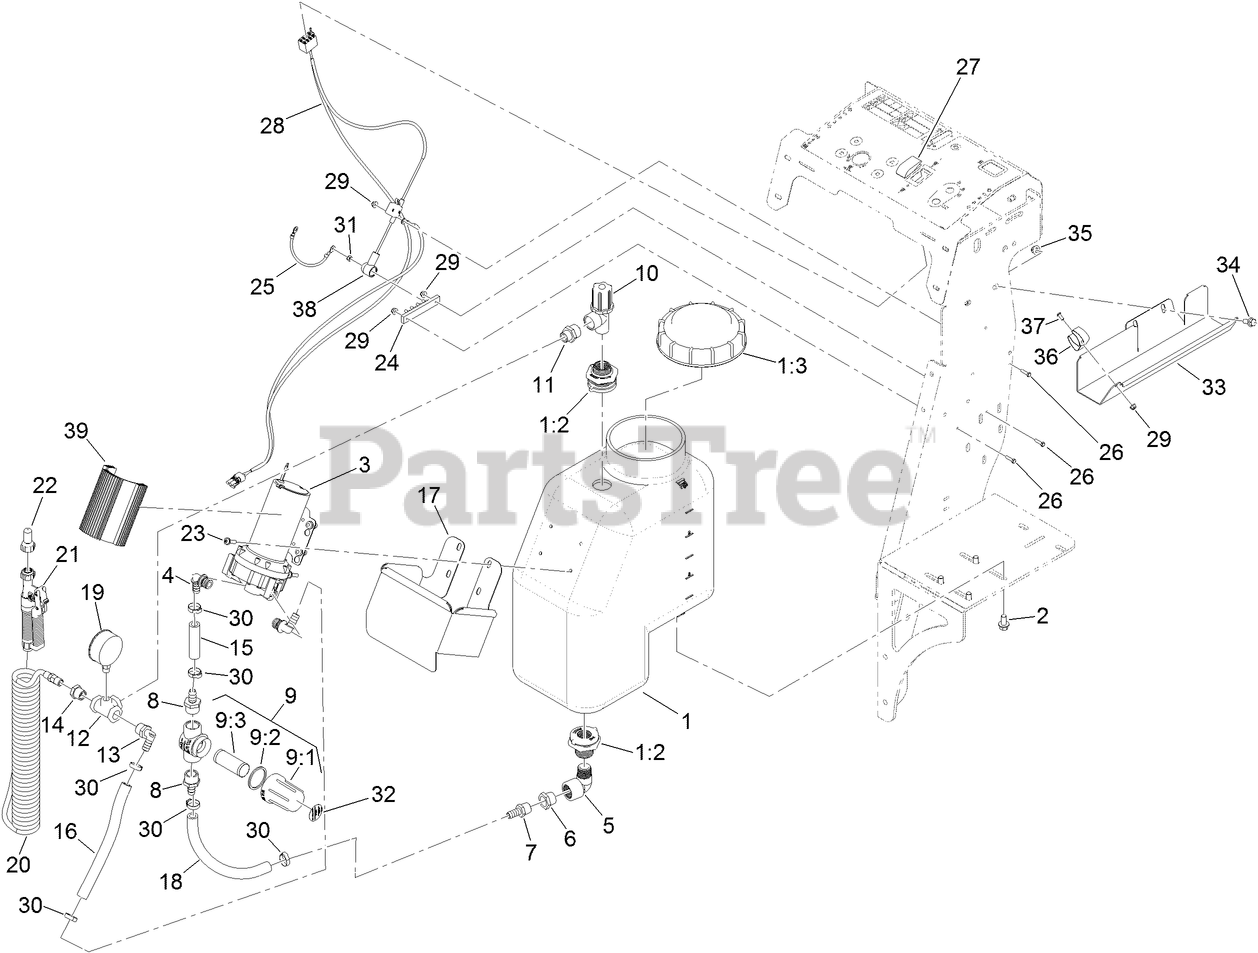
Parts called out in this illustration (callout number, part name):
1	ASM-TANK, ISO, 7GAL
1:2	FITTING-BULKHEAD
1:3	CAP-TANK, SPRAY
2	SCREW-HHF
3	PUMP-5.3 GPM
4	FITTING-ELBOW, BARBED
5	ELBOW-90 DEG
6	REDUCER-BUSHING, PLASTIC
7	FITTING-HOSEBARB
8	FITTING-STRAIGHT
9	STRAINER-INLINE
9:1	BOWL-STRAINER
9:2	GASKET-HEAD, LINE STRAINER
9:3	SCREEN-STRAINER, 50 MESH
10	VALVE-THROTTLE
11	FITTING-NIPPLE
12	FITTING-CROSS
13	FITTING-ELBOW, HOSEBARB
14	FITTING-REDUCER
15	HOSE-SPRAY
16	HOSE-SPRAY
17	GUARD-PUMP, ISO
18	HOSE-SPRAY
19	GAUGE-PLAIN
20	HOSE-COILED, 15 FT
21	GUN-SPRAY, SPOT
22	TIP-SPRAY, #12 SPOT
23	SCREW-HSBHF
24	BLOCK-TERMINAL
25	HARNESS-WIRE, JUMPER
26	SCREW-HH
27	SWITCH-ROCKER
28	HARNESS-ACCESSORY
29	NUT-HEX FLANGE
30	CLAMP-OETIKER, 167
31	NUT-HEX
32	DECAL-CAP, STRAINER
33	TRAY-GUN, 7GAL RT
34	SCREW-HHF
35	NUT-HEX FLANGE
36	HOLDER-TOOL, CLIP
37	SCREW-HSBH
38	INSULATOR-SOLENOID
39	HEATSINK-3.0"
